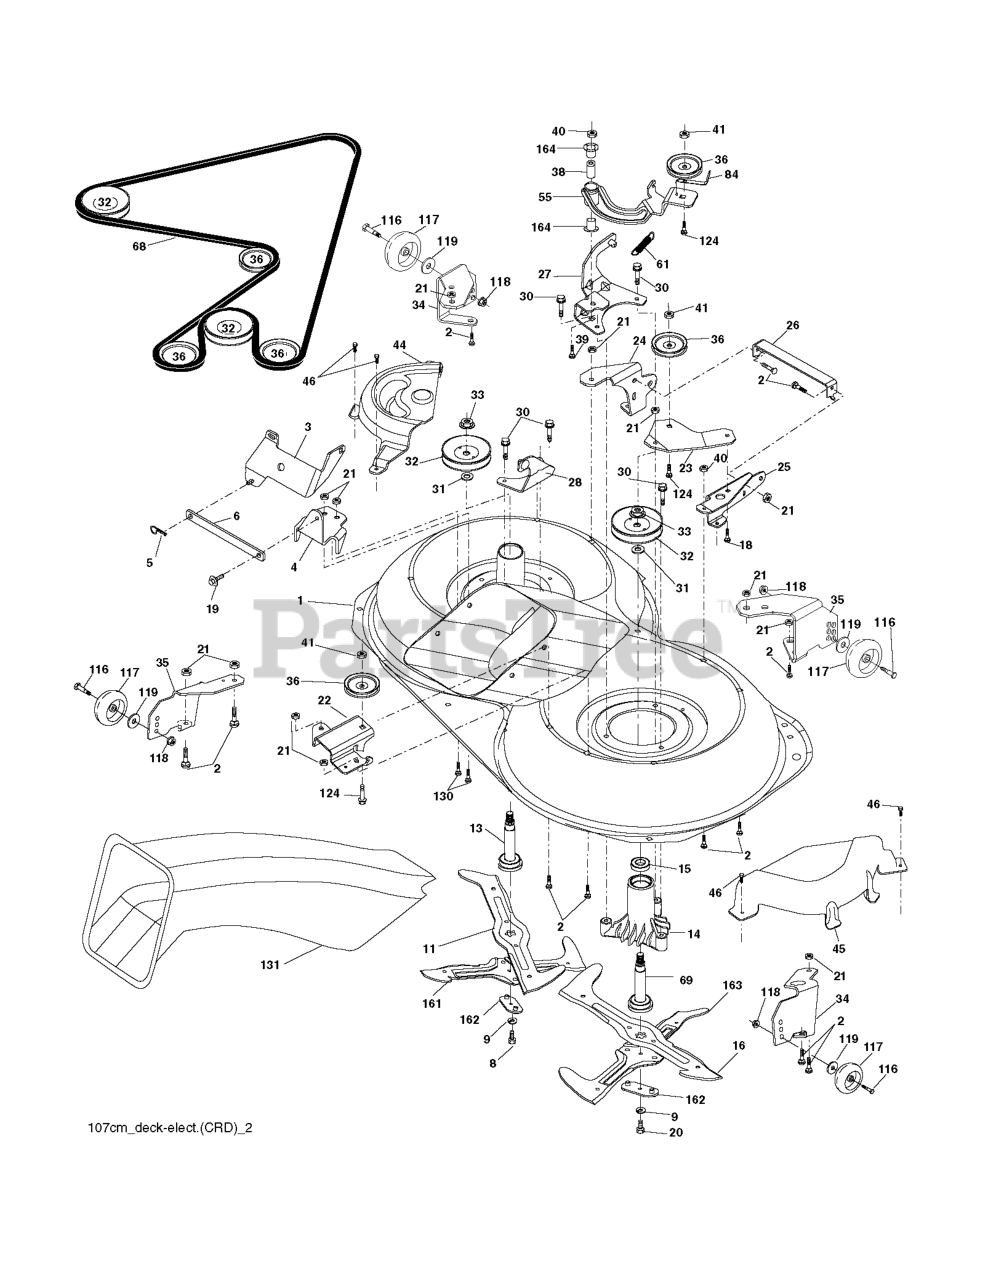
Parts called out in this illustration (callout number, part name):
1	Housing Asm. Mower 107 CRD
2	RP BOLT 5/16-18 X3/4 ZN/YEL GR
5	RETAINER-SPRNG RB
6	BAR.SWAY.92.CRD
8	BOLT.3/8-24X1.25 GR8
9	LOCKWASHER
11	BLADE.3N1.LH.CRD
13	SHAFT ASM VENT
14	HOUSING.MANDREL.VENTED (MACHD)
16	BLADE.3N1.RH.CRD
19	BOLT SHD 5/16-18
20	BOLT.3/8-24X1.25GR8. LHTHRD
21	LOCKNUT
22	BRACKET.IDLER.RR.107.CRD
25	BRACKET RF
26	SUPPORT
28	BRACKET
30	SCREW, WASHER HEAD
31	WASHER.SPACER.MANDREL
33	NUT.FLANGE.LOCK.TOP
34	BRACKET
35	BRACKET
36	PULLEY.IDLER.4.25
41	NUT LOCK FLG 3/8-16 UNC
45	COVER.MANDREL.RH.CRD
46	SCREW.1/4-20X5/8
55	ARM.IDLER.107.CRD
68	HEX-BELT 107 MOWER
69	SHAFT.ASM.W/LWR.BRG.RH.THREAD
84	KEEPER, BELT IDLER
116	BOLT.SHOULDER.3/8-16X3-5/8.
117	RP WHEEL. GUAGE RALLY
118	NUT LOCK FLG 3/8-16 UNC
119	WASHER
124	BOLT.3/8-16X1.50
130	BOLT.CARR.SQNK.5/16-18UNC.X3/4
131	CHUTE BAGGER
163	BLADE.CROSS.RH.CRD.107
164	BRNG T
